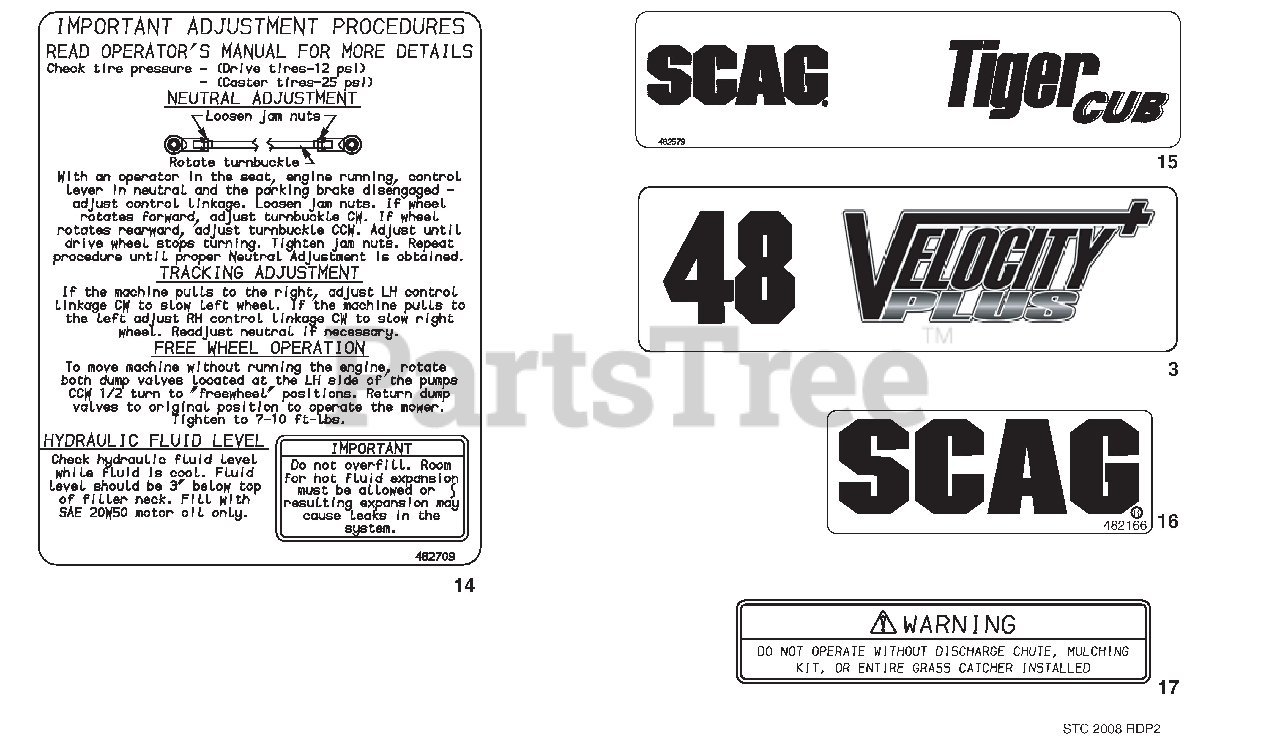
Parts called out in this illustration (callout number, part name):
3	Decal
14	Decal, Seat Support
15	Decal, Rear Bumper
16	Decal, Front Footplate
17	Decal, Discharge Chute
